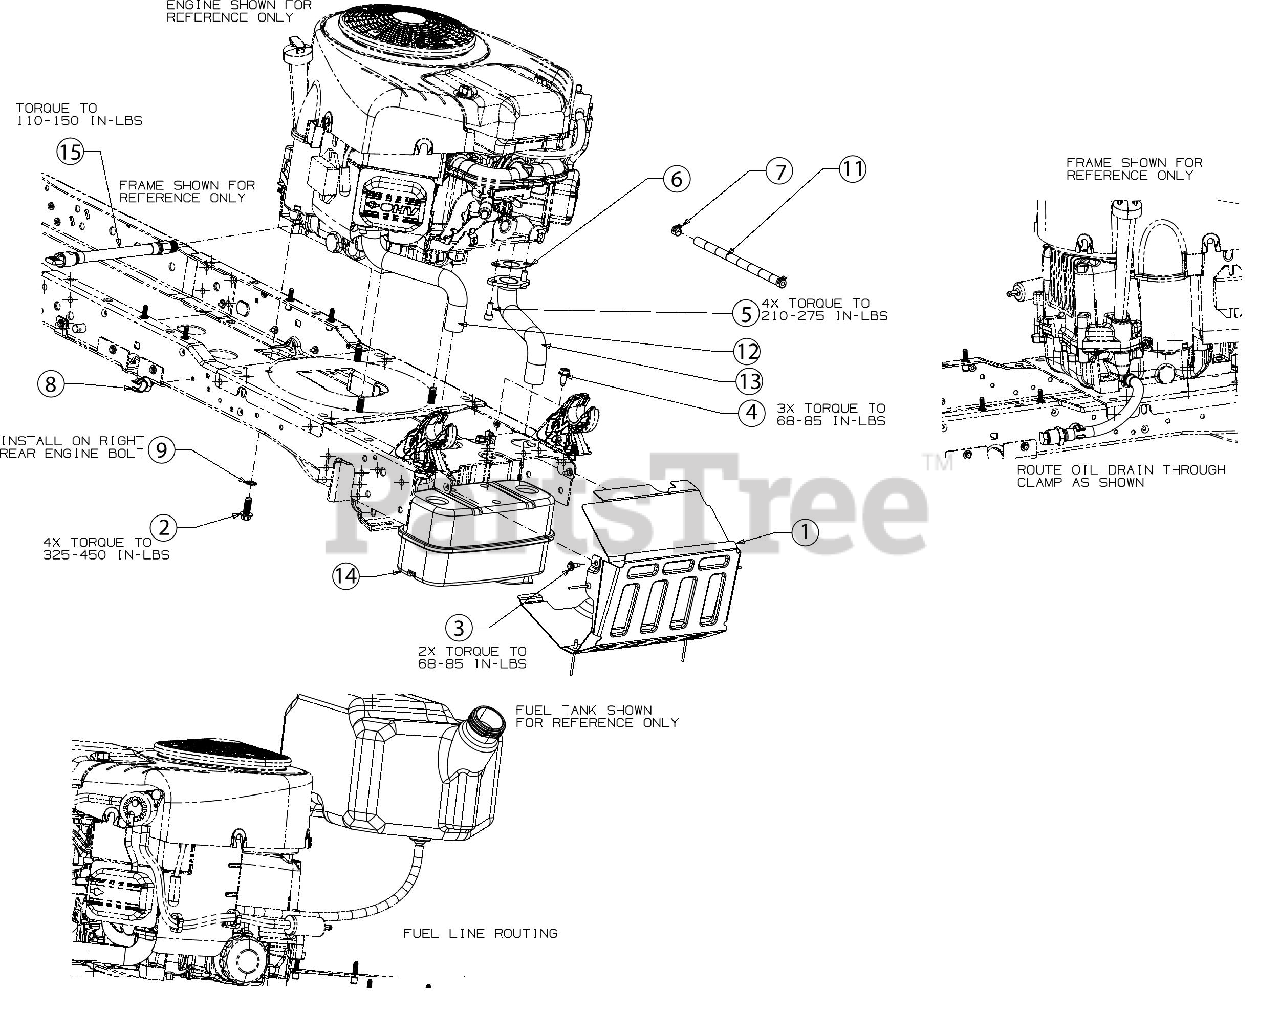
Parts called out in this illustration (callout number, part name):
1	MUFFLER SHIELD ASSEMBLY
2	SCREW 3/8-16 x 1
3	SCREW M6-1 x .625
4	SCREW M8-1.25 x .750
5	SCREW 5/16-18 x .625
6	MUFFLER GASKET
7	HOSE CLAMP 1/20
8	DRAIN HOSE CLIP
9	LOCK WASHER 3/8
10	OIL 10W30 (NOT SERVICEABLE)
11	FUEL HOSE LOW PERMEATION
12	EXHAUST PIPE (RH) (B&S)
13	EXHAUST PIPE (LH) (B&S)
14	EXHAUST MUFFLER (TWIN)
15	OIL DRAIN HOSE 3/8 NPT
